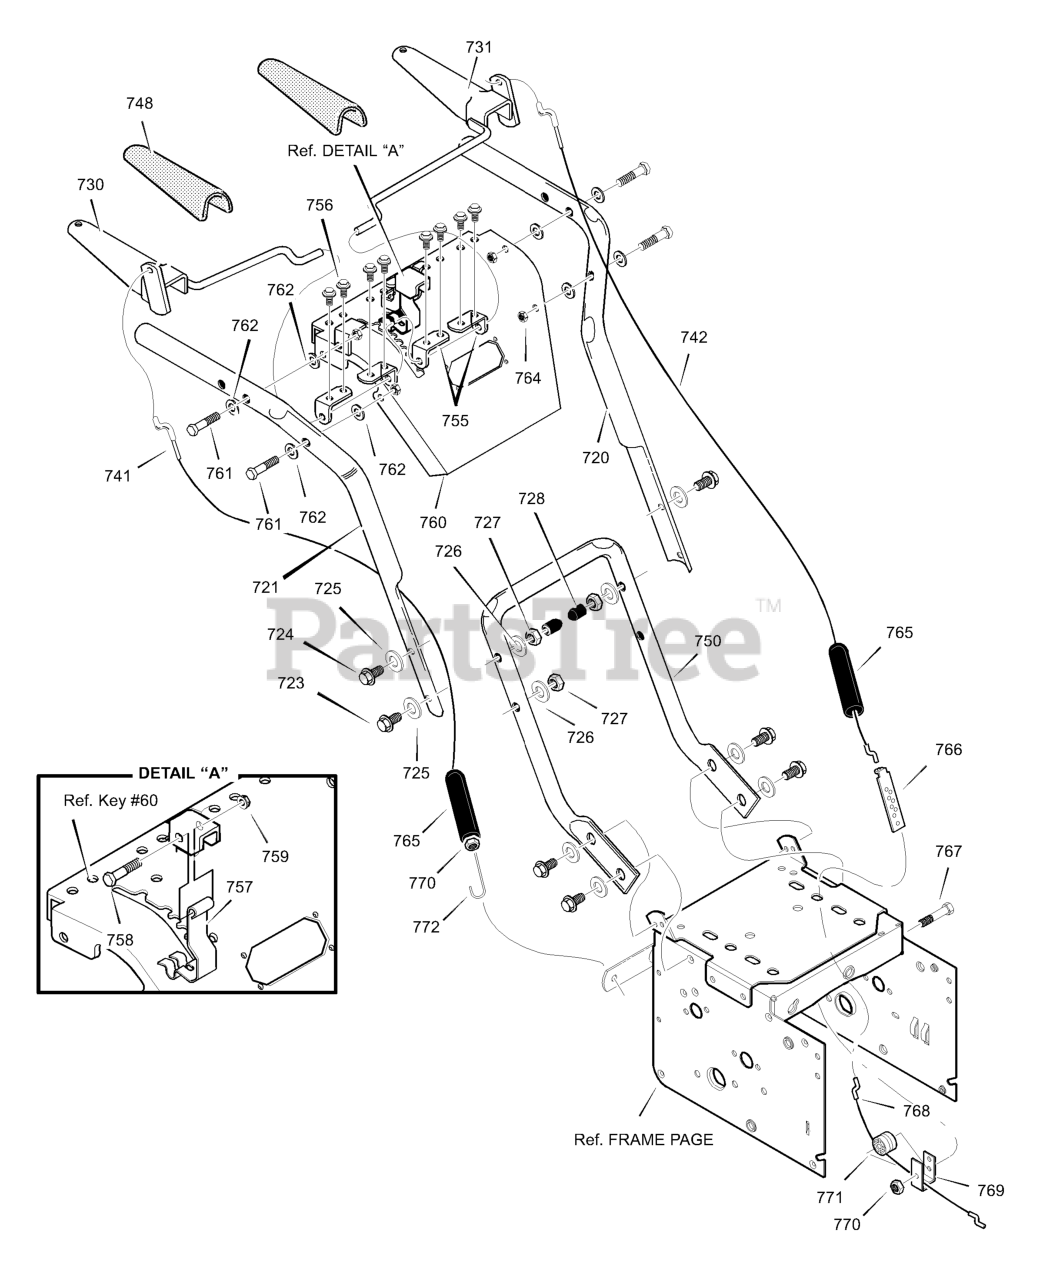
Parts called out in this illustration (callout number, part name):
720	HANDLE, UPPER LH
721	HANDLE, UPPER RH
723	SCREW
724	SCREW
725	WASHER, FLAT
726	WASHER, SPTLK
727	NUT, HEX
728	STOP, PLASTIC
730	LEVER, ASSY CLUTCH DRIVE RH
731	LEVER, ASSY CLUTCH DRIVE LH
741	CABLE, AUGER CLUTCH
742	CABLE, TRACTON DRIVE
743	BRACKET, CABLE ADJUSTER
745	NUT, 1/4-20
748	GRIP, CLUTCH HANDLE
750	HANDLE, LOWER
751	SCREW, TAP 5/16-18 X .75
752	WASHER
754	SCREW
755	BRKT, ROD
756	SCREW
757	SPRING, CAM LOCK
758	BOLT, HEX
759	NUT
761	SCREW
762	WASHER, FLAT
764	NUT, HEX
765	BOOT, CLUTCH SPRING
767	BOLT, HEX 1/4-20 X 1.50 YZ
768	CABLE, LOWER DRIVE 12"
769	BRACKET, CABLE SPOOL YZ
770	NUT
771	SPOOL-CABLE, AUGRT CLUTCH
772	SPRING, AUGER CLUTCH
